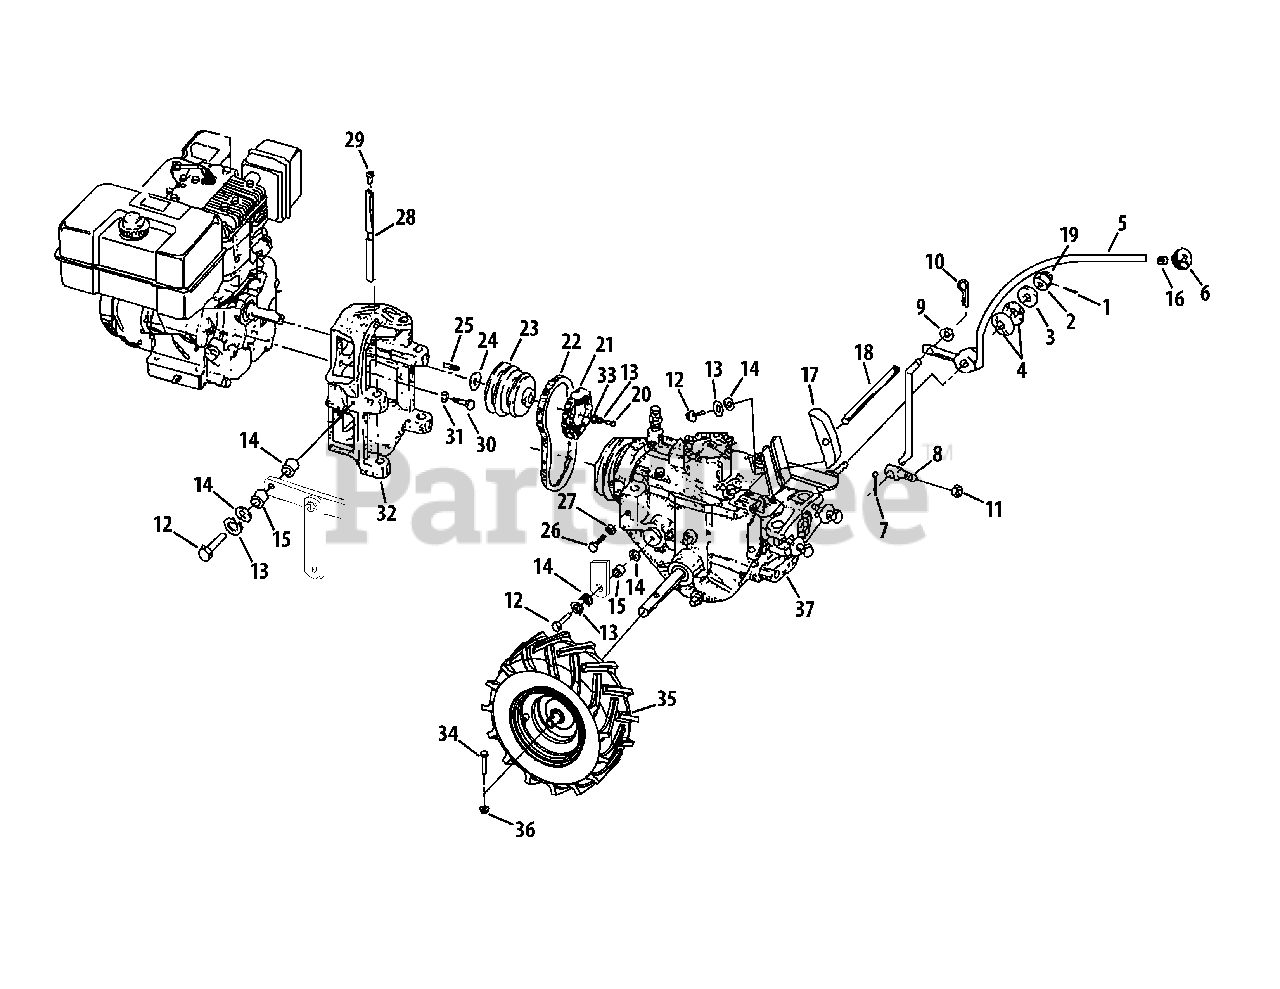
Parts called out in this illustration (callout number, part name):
1	Spring Pin, 1/8"
2	Flat Washer, .510 x 1.0 x .125
3	Shoulder Washer, 1.25 x .50 x .25
4	Disc Spring Washer
5	Wheel Speed Shift Lever
7	Cotter Pin, 3/32" x 1"
9	Flat Washer, .344 x .688 x .065
10	Hair Pin Cotter
11	Hex Locknut, 5/16"-18
12	Hex Head Screw, 3/8"-16 x 1"
13	Lockwasher, 3/8"
14	Flat Washer, .406 x .810 x .051
15	Bushing Spacer, .5 x .375 x .3
16	Retaining Ring
17	Belt Adjustment, 3-7/8"
18	Belt Adjustment Rod
19	Hex Nut, 1/2"-20
20	Hex Head Screw, 3/8"-24 x 1.75
21	Reverse Disc
22	Forward Drive Belt
23	Engine Power Take-off Pulley
24	Flat Washer, .766 x 1.0 x .031
24	Flat Washer, .766 x 1.0 x .062
25	Engine Pulley Key, 3/16"x 2-1/2"
26	Hex Head Screw, 5/16"-18 x 1"
27	Hex Nut, 5/16"-18
28	Engine Mounting Bar
29	Thread Protector Plug
30	Hex Head Screw, 5/16-24 x 1.25
31	Lockwasher, 5/16"
33	Flat Washer, .406 x 1.0 x .105
34	Hex Screw, 1/4"-20 x 1-1/2"
35	Wheel Assembly, 16 x 4.6 x 8"
35	Tire, 16.2 x 4.6
36	Hex Flange Nut, 1/4"-20
37	Clutch Bracket
